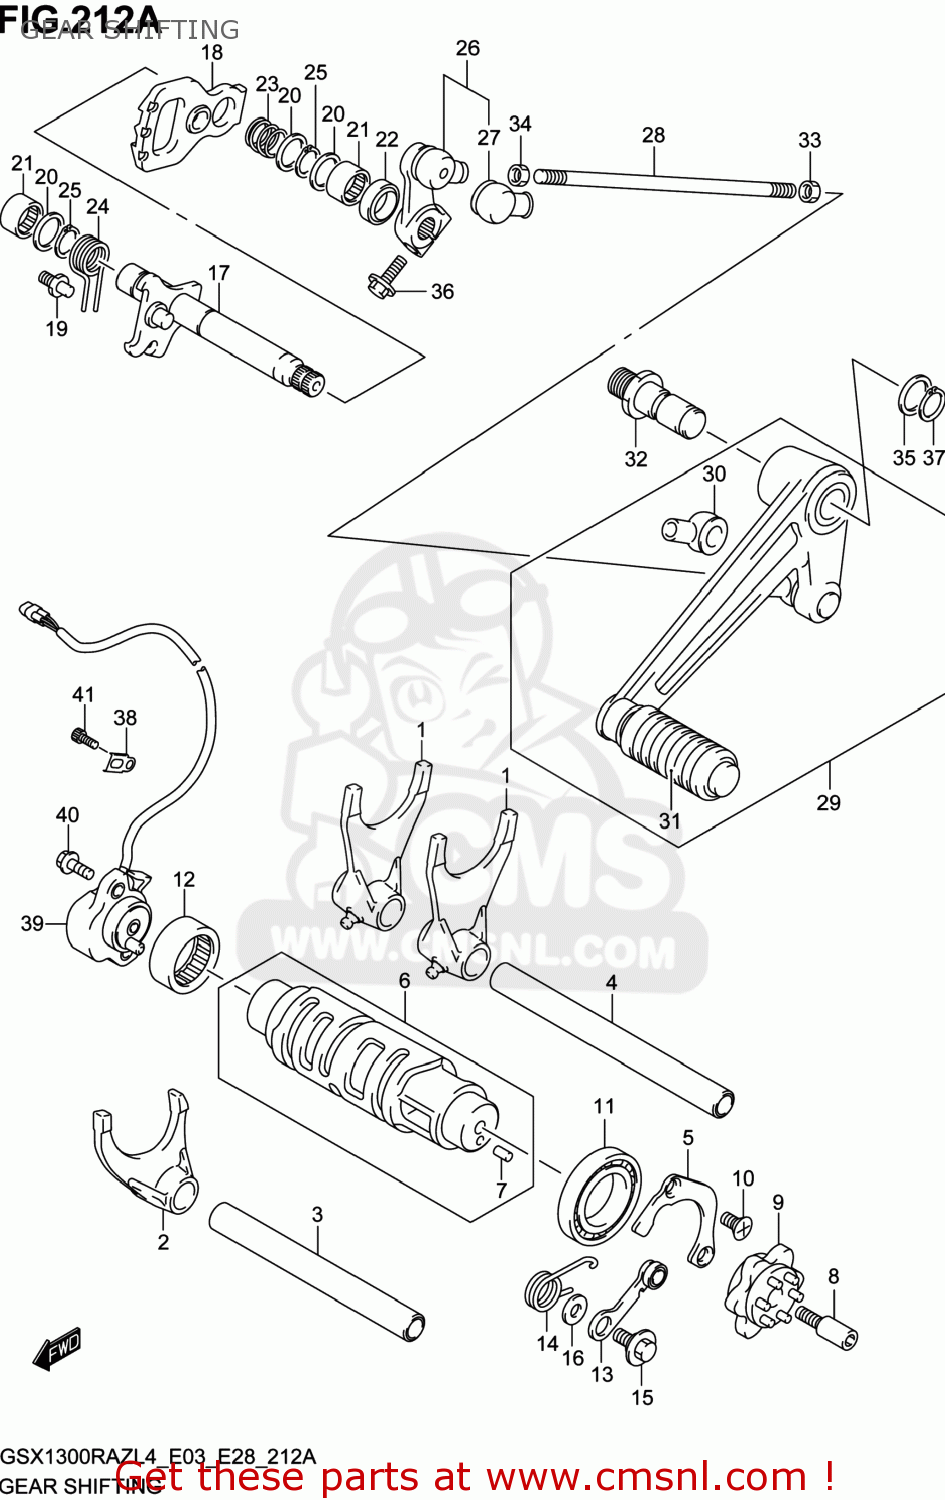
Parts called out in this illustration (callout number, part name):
1	FORK,GEAR SHIFT NO.1
2	FORK,GEAR SHIFT NO.3
3	SHAFT,SHIFT FORK NO.2(L:132)
4	SHAFT,GEAR SHIFT FORK(L:152)
5	RETAINER,SHIFT CAM BEARING
6	CAM,GEAR SHIFT
7	PIN
8	BOLT,GEAR SHIFT CAM PLATE
9	PLATE,GEAR SHIFT CAM
10	SCREW(6X12)
11	BEARING(25X47X8)
12	BEARING(25X32X12)
13	STOPPER,SHIFT CAM
14	SPRING,STOPPER ARM
15	BOLT(6X14.3)
16	WASHER
17	SHAFT,GEAR SHIFT
18	PLATE,GEAR SHIFT CAM DRIVE
19	STOPPER,GEAR SHIFT ARM
20	SHIM(14X22X1)
21	BEARING(14X20X12)
22	SEAL,OIL(14X22X7.3)
23	SPRING
24	SPRING
25	CIRCLIP
26	ARM,GEAR SHIFT LINK
27	COVER,DUST
28	ROD,GEAR SHAFT LINK
29	LEVER ASSY,GEAR SHIFT
30	COVER,DUST
31	RUBBER,GEAR SHIFT PEDAL
32	SHAFT,GEAR SHIFT LEVER
33	NUT
34	NUT
35	WASHER(12.5X20X1)
36	BOLT
37	CIRCLIP
38	CLAMP,GENERATOR LEAD WIRE
39	SENSOR ASSY,GEAR POSITION
40	BOLT
41	BOLT
